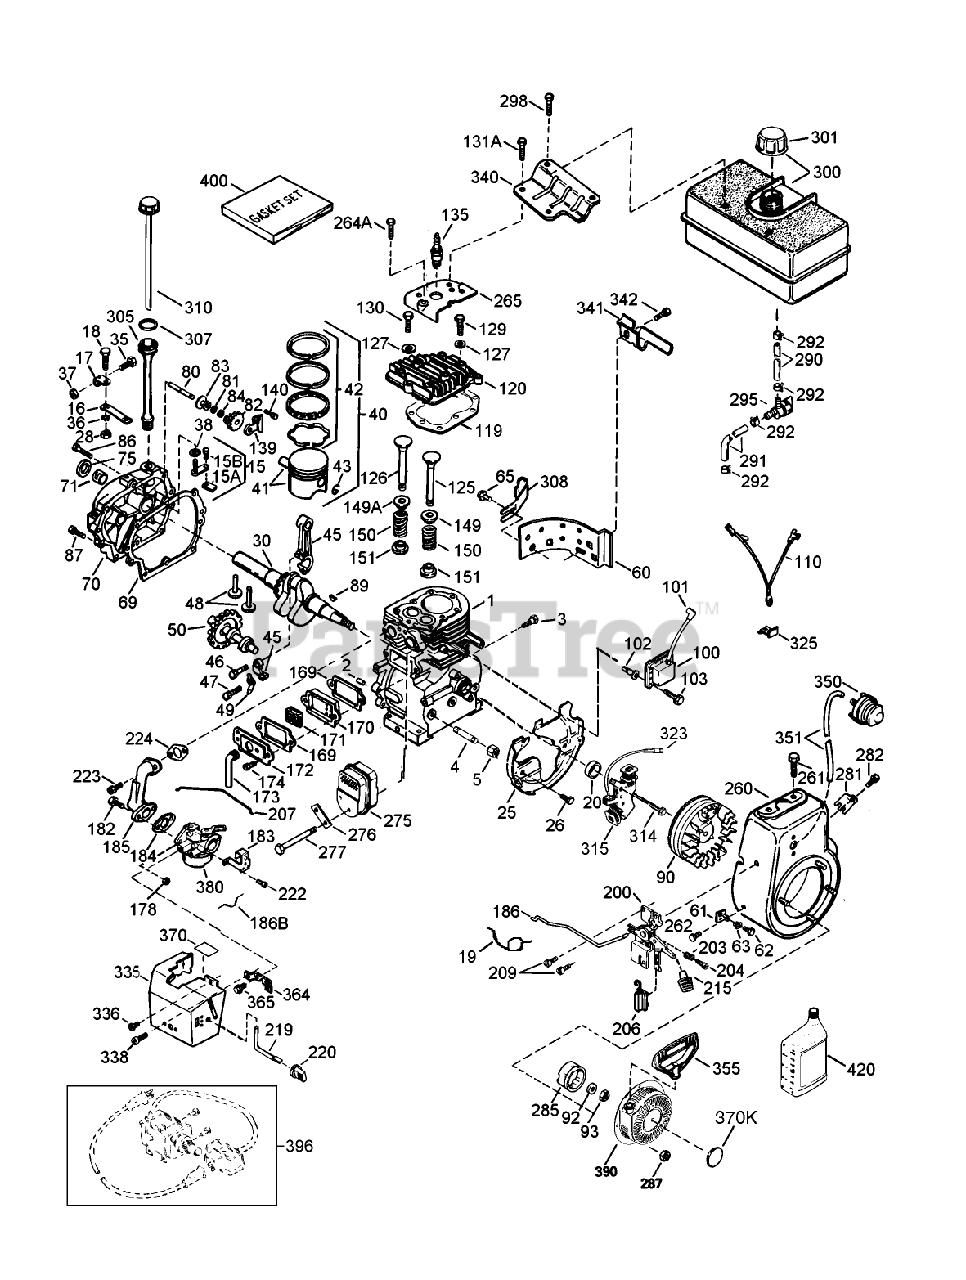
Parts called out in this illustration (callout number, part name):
1	Cylinder Asm (Includes 2, 20, 72)
2	Pin-Dowel
3	Screw (1/4-20x1/2)
4	Nipple-Pipe
5	Cap-Pipe
15	Rod, Governor (Incl. Nos.62 63)
15A	Yoke-Governor
15B	Screw (6-40x5/16)
16	Lever-Governor
17	Clamp-Lever, Governor
18	Screw
19	Spring-Throttle
20	Seal-Oil
25	Baffle-Housing, Blower
26	Screw (1/4-20x19/32)
28	Nut-Lock
30	Crankshaft
35	Screw
36	Washer-Lock
37	Nut-Lock
38	Ring-Retaining
40	Piston, Pin Ring Assy.(Std.) (Incl. Ref. #24A, 25 26)
40	Piston, Pin Ring Assy. (.010 oversize) (Incl. Ref. #24A, 25 26)
40	Piston, Pin Ring Assy. (.020 oversize) (Incl. Ref. #24A, 25 26)
41	Piston Pin Assy. (Std.) (Incl. Ref. #26)
41	Piston Pin Assy. (.010 oversize) (Incl. Ref. #26)
41	Piston Pin Assy. (.020 oversize) (Incl. Ref. #26)
42	Ring Set (Std.)
42	Ring Set (.010" OS)
42	Ring Set (.020" OS)
45	Rod Assy., Connecting (Incl. Ref. #28 28A)
46	Bolt-Rod
47	Bolt-Rod
48	Lifter-Valve
49	Dipper-Oil
50	Camshaft (MCR)
60	Extension-Housing, Blower
61	Bracket
62	Screw (8-32 x 3/8)
63	Grommet
65	Screw
69	Gasket-Cover, Cylinder
70	Cover-Cylinder (Includes 71, 75, 80)
71	2025A77 WIZARD ROTA
75	Seal-Oil
80	Shaft-Governor
81	Washer-Flat
82	Gear Assy., Governor (Incl. Ref. #45)
83	Spool-Governor
84	Ring-Retaining
86	Screw (1/4-20x1-3/16)
87	Screw (1/4-20x1-11/16)
89	Key-Flywheel
90	Flywheel ASM
92	Washer-Belleville
93	Nut-Flywheel
100	Solid State ASM
101	Cover-Spark Plug
103	Screw (T-15, 10-24 x 15/16)
110	Ground Wire
119	Gasket-Head, Cylinder
120	Head-Cylinder
125	Valve, Exhaust (Standard)(Incl. No. 9)
125	Valve, Exhaust (1/32" oversize)(Incl. No. 9)
126	Valve, Intake (Std.) (Incl. Ref. #58)
126	Valve, Intake (1/32" oversize) (Incl. Ref. #58)
127	Washer-Flat
129	Screw (5/16-18x1-25/32)
130B	Screw (5/16-18x1-1/2)
131A	Screw
135	Spark Plug-Resistor (R J19 L M)
139	Bracket-Gear, Governor
140	Screw (10-24x1/2)
149	Cap-Spring, Valve
149A	51106 GILSON ROTARY
150	Spring-Valve
151	Keeper-Spring, Valve
169	Gasket-Cover, Valve
170	Body-Breather
171	Element-Breather
172	Cover-Valve
173	Tube-Breather
174	Screw
178	Nut and Lock Washer (1/4-28)
182	Screw (1/4-28x1)
183A	Bracket-Choke
184	Gasket-Carburetor To Intake Pipe
185	Pipe-Intake
186	Link-Governor
186A	Spring-Choke
200	Bracket-Control (Includes 19, 203, 204, 206)
203	Spring-Compression
204	Screw
206	Terminal
207	Link-Throttle
209	Screw (10-32 x 1/2)
215	Knob-Control
219	Rod-Choke
220	Knob-Control
222	Screw (10-32 x 1/2)
223	Screw (T-30, 5/16-18x1-3/32)
224	Gasket-Pipe, Intake
260	Housing-Blower
261	Screw (5/16-18x3/4)
262	Screw
264A	Screw (1/2-20x5/8)
265	Cover-Cylinder Head
275	Muffler
276	62513 SNWTHWR W/284
277	Screw (5/16-18x4-3/16)
281	Screw
282	Screw (8-32 x 3/8)
285	Cup-Starter
287	Nut and Lock Washer (1/4-28)
290	Line-Fuel (8.62)
291	Line-Fuel
292	Clamp-Line, Fuel
295	Valve-Shut Off, Fuel
298	Screw (1/4-15x7/8)
300	Tank-Fuel (Includes 292, 301)
301	Cap-Fuel
305	Tube-Fill, Oil
307	O-Ring
308	Clip-Tube, Fill
310	Gauge Oil ASM
314	Screw (1/4-20 x 3/4)
315	Coil-Alternator, 18 Watt (Includes 323)
323	Terminal
325	Clip-Wire
335	Cover-Carburetor
336	Screw (10-32x1/2)
338	Screw (10-32 x 3/8)
340	Bracket-Tank, Fuel
341	Bracket-Tank, Fuel (Black)
342	Screw (1/4-20x19/32)
350	Primer-Asm
351	Line-Primer
355	Handle-Starter, Mitten Grip
364	Bracket-Carburetor
365	Screw (8-32x27/64)
370	Decal-Lubrication
370K	Decal-Tecumseh Logo for Top of Recoil Starter
380	Carburetor (Incl. Ref. #184)
390	Starter-Rewind
396	Starter-Electric (110 Volt)
400	Gasket Set
420	Oil-Engine (SAE 5W30)
